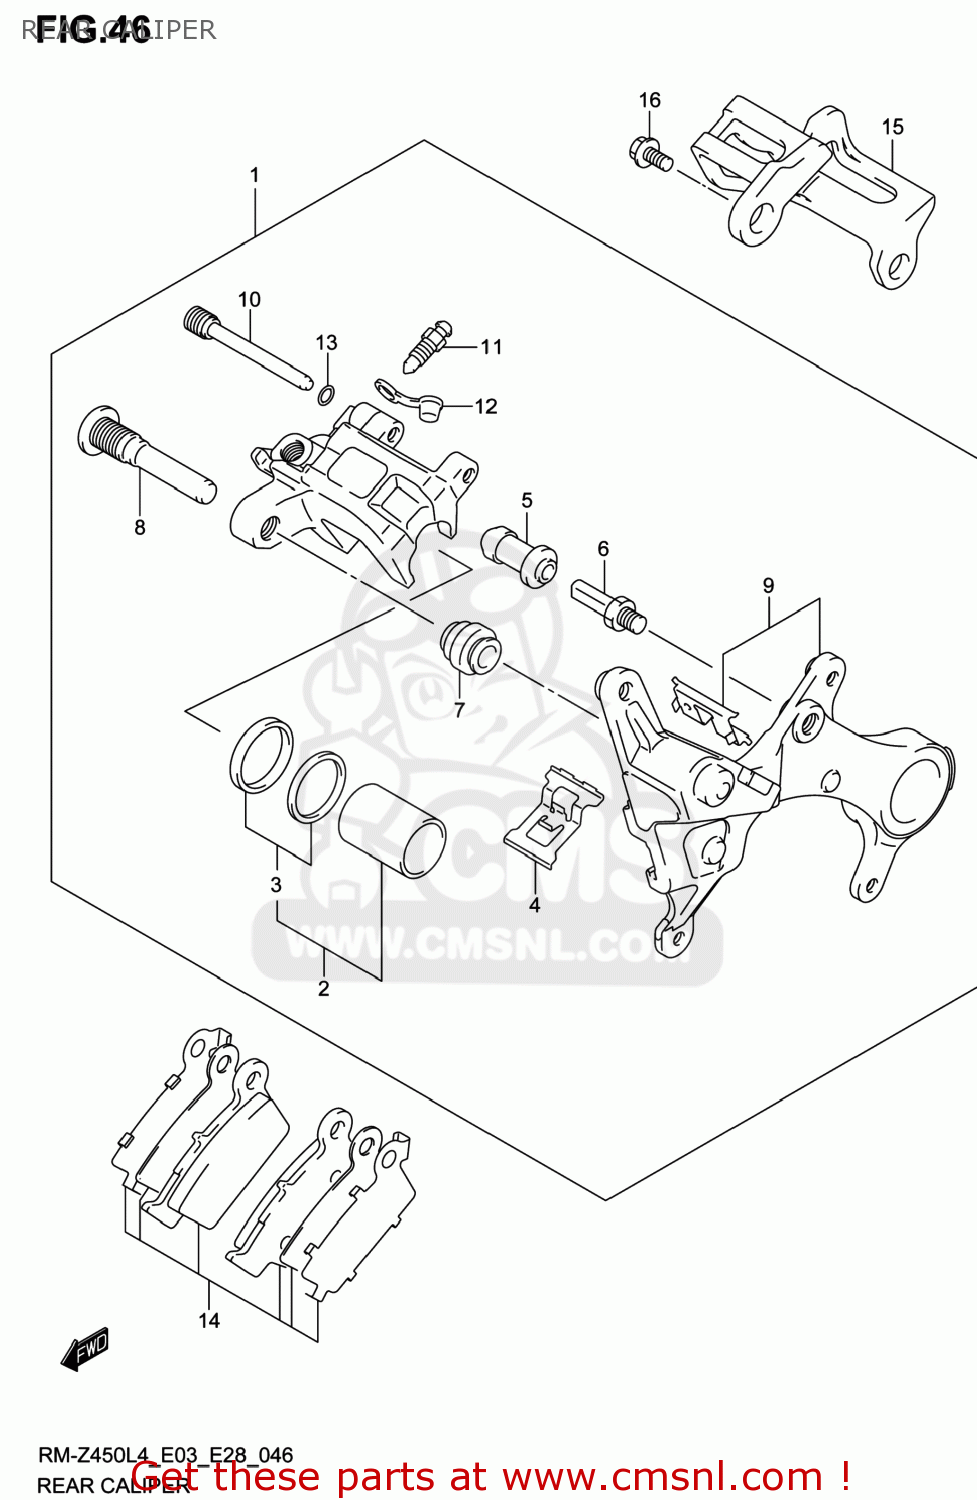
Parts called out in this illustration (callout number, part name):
1	CALIPER ASSY,RR
2	PISTON SET
3	SEAL SET,PISTON
4	SPRING,PAD
5	BOOT
6	PIN,BOLT
7	BOOT
8	PIN,BOLT
9	BRACKET,RR CALIPER
10	PIN,HANGER
11	BLEEDER
12	CAP,BLEEDER
13	RING,STOPPER
14	PAD & SHIM SET (NAS)
15	GUARD,RR CALIPER
16	BOLT(6X12)
